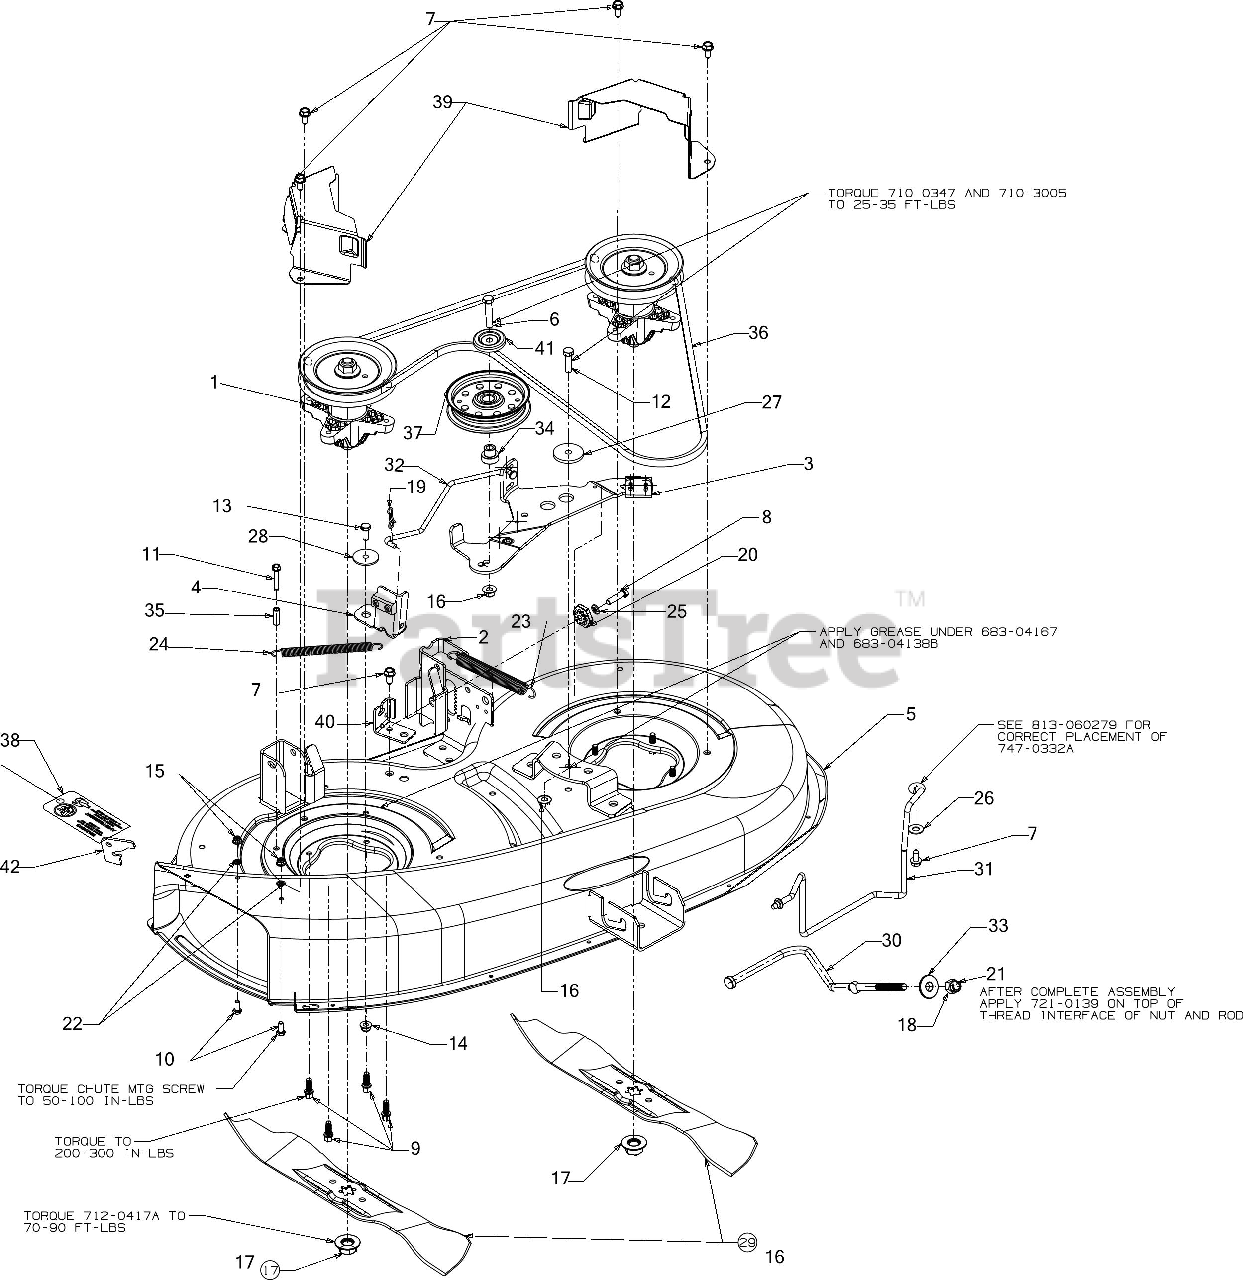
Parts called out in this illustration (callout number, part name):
1	SPINDLE ASSEMBLY
2	DECK HANGER BRACKET ASSEMBLY (LH)
3	42" DECK BRAKE ASSEMBLY
4	42" DECK BRAKE ASSEMBLY
5	38" DECK ASSEMBLY
6	HEX SCREW 3/8-16 x 1.75 GR5
7	SCREW 5/16-18 x .750
8	SCREW 5/16-18 x 1.25 GR5
9	SCREW 5/16-18 X .875
10	SCREW 1/4-20 x .620 GR5
11	SCREW 1/4-20 x 1.50"
12	SCREW 3/8-16 x 1.25 GR5
13	SCREW 5/16-18 x .75 GR5
14	FLANGE LOCK NUT 5/16-18
15	FLANGE LOCK NUT
17	HEX NUT
19	BOW TIE COTTER PIN 1/4-5/16
20	DECK ADJUSTMENT
21	LOCTITE SEALANT (NOT SERVICEABLE)
22	RETAINER-BOLT .25ID x .50OD
23	EXTENSION SPRING
24	EXTENSION SPRING
25	LOCK WASHER 5/16
26	FLAT WASHER
27	SHOULDER SPACER
28	SHOULDER SPACER
29	19.38" BLADE (3N1)
30	FRONT DECK ADJUSTMENT ROD
31	BELT KEEPER ROD
32	BRAKE CONTROL ROD
33	LIFT PIVOT CUP
34	SHOULDER SPACER
35	SPACER
36	V-BELT A-SEC x 77.15
37	IDLER PULLEY 4.25 DIA
38	(NOT SERVICEABLE)
39	BELT COVER
40	DECK CABLE BRACKET
41	IDLER PULLEY CAP
42	(NOT SERVICEABLE)
